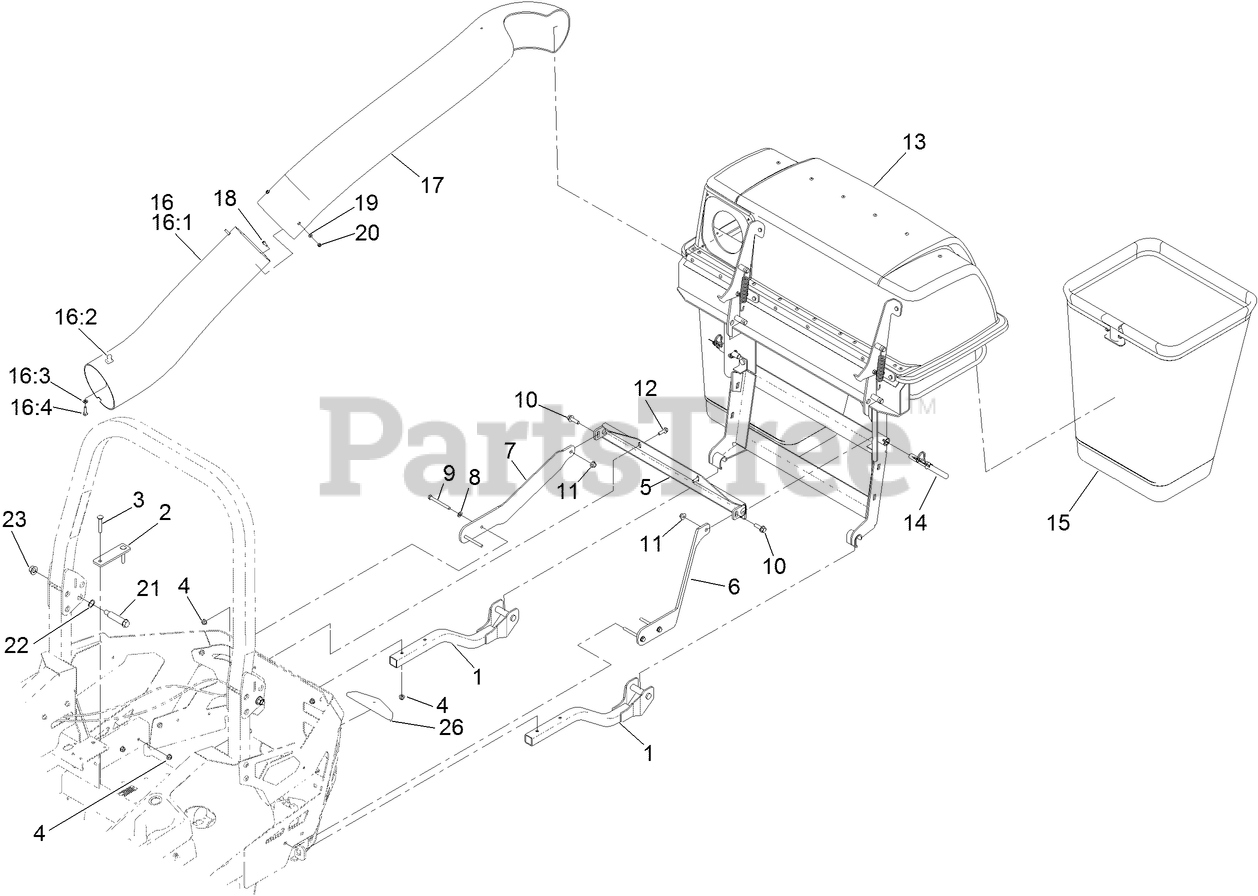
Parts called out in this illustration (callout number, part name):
1	SUPPORT, LOWER [BLACK]
2	PLATE-BACKER
3	BOLT-CARR
4	NUT-HF, NI
5	SUPPORT-BAGGER, UPPER
6	BRACKET-UPPER, LH
7	BRACKET-UPPER, RH
8	WASHER-PLAIN
9	SCREW-HH
10	SCREW-HHF
11	NUT-HF, NI
12	SCREW-HHF
13	TWIN BAG HOOD ASM
14	PIN-MOUNT, BAGGER
15	BAG AND FRAME ASM
16	LOWER TUBE ASM
16:1	TUBE-LOWER
16:2	LATCH-KEEPER
16:3	WASHER-FLAT
16:4	SCREW-PPH
17	TUBE-UPPER
18	SCREW-HWH
19	WASHER-FLAT
20	NUT-LOCK, NI
21	BOLT-SHOULDER
22	WASHER-WAVE
23	NUT-LOCK
26	COVER-HITCH
